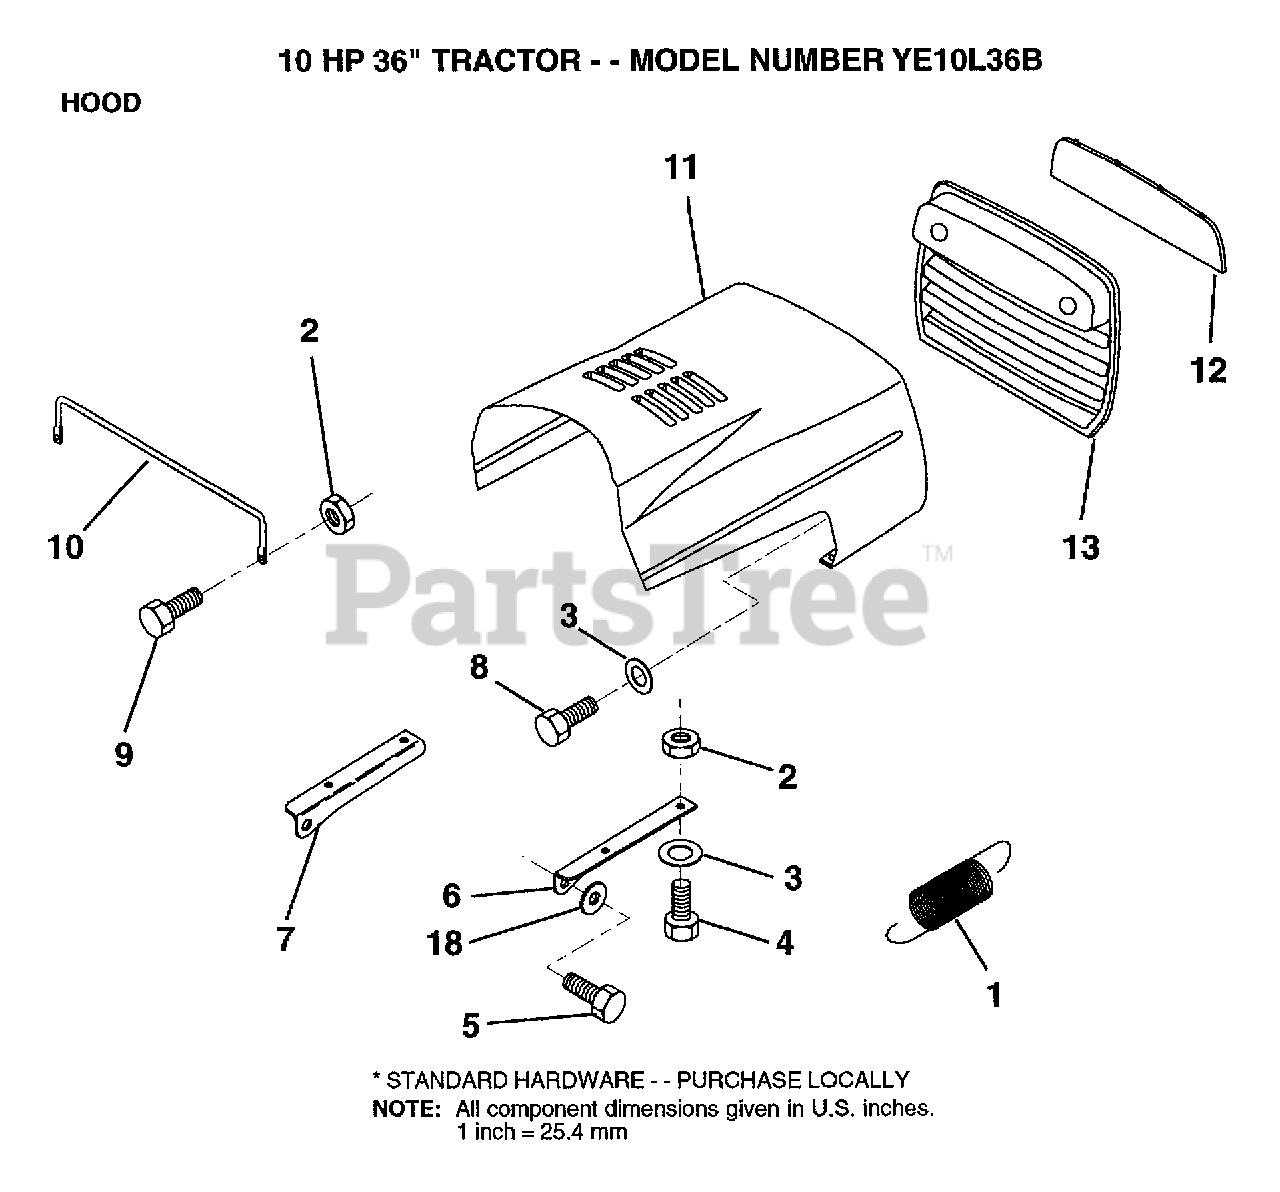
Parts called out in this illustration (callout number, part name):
1	EXT SPRING
2	NUT
3	WASHER
4	BOLT
6	BRKT HOOD RH
7	BRKT HOOD LH
10	"BRACE,HOOD"
11	HOOD
12	LENS
13	GRILL
18	WASHER
